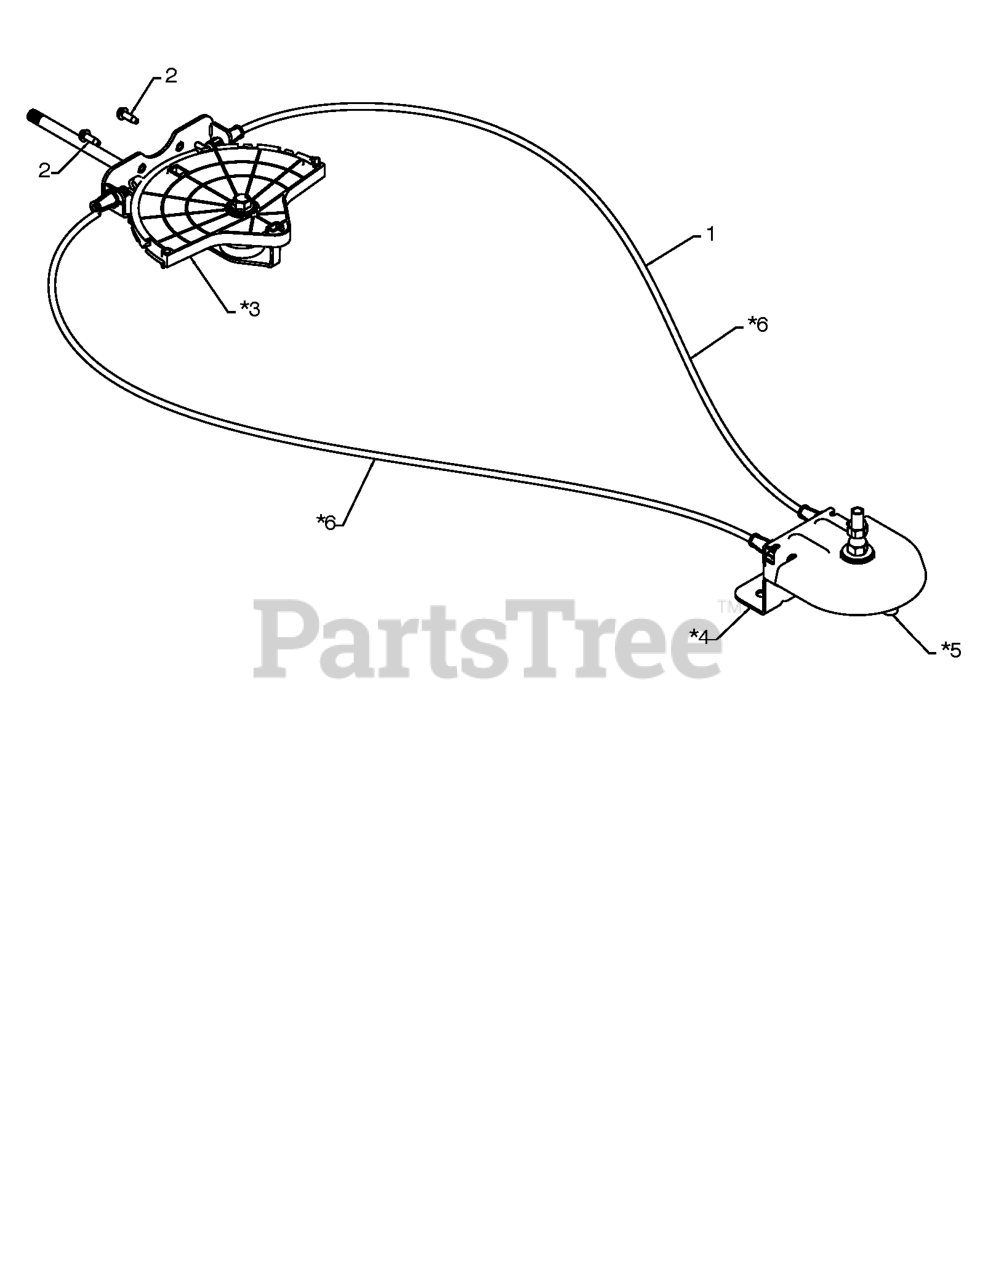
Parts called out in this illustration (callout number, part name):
1	LEVER/CABLE.
2	SCREW #10-24 X 5/8
3	CHUTE.ROT.HEAD.SERVICE
4	BRACKET.PIVOT.SNOW.GRAY.
5	SNOW.PIVOT.PULLY
6	CABLE.CHUTE.ROTATION.GREY.SNOW
